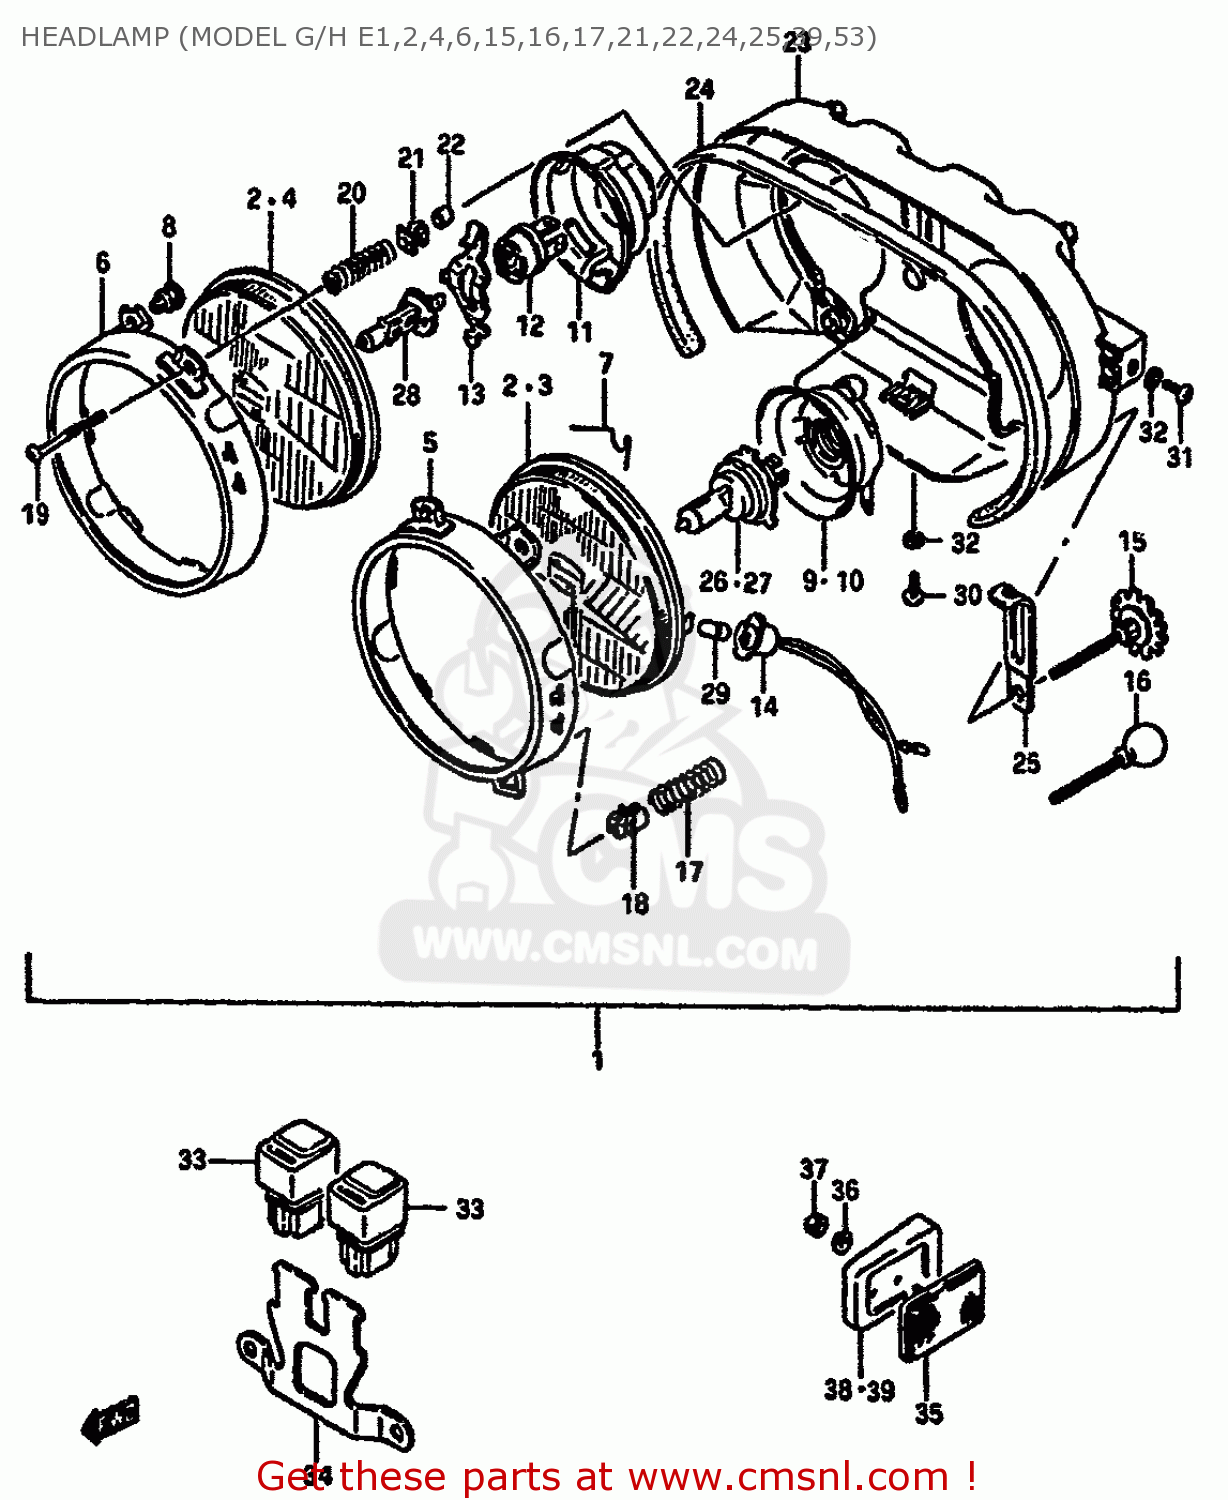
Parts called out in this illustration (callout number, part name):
1	HEADLAMP ASSY
2	UNIT
3	LAMP UNIT,L
4	UNIT,RH
5	RING,RETAINING,LEFT
6	RING,RETAINING,RIGHT
7	SPRING
8	SCREW,SPHERICAL
9	COVER,SOCKET
10	COVER,SOCKET
11	COVER, SOCKET,LH
12	ADAPTER
13	SPRING,PLATE
14	SOCKET
15	SCREW,ADJUSTER
16	SCREW,ADJUSTER
17	SPRING
18	NUT
19	SCREW,ADJUSTER
20	SPRING
21	NUT
22	CAP,SCREW
23	HOUSING,HEADLAMP
24	GASKET (NAS)
25	CLAMP
26	BULB(12V60/55W,H4)
27	BULB(12V60/55W,H4)
28	BULB(12V55W/H1/P14.5S/OSRA,PHI
29	BULB(12V4W)
30	SCREW
31	SCREW
32	WASHER,LOCK
33	RELAY, ANTINOSE DIVE FORK
34	BRACKET,HEADLAMP RELAY
35	REFLEX REFLECTOR, FRONT SIDE
36	WASHER,5MM
37	NUT ,5MM
38	SPACER,FRONT SIDE,REAR,RIGHT
39	SPACER,FRONT SIDE,REAR,LEFT
